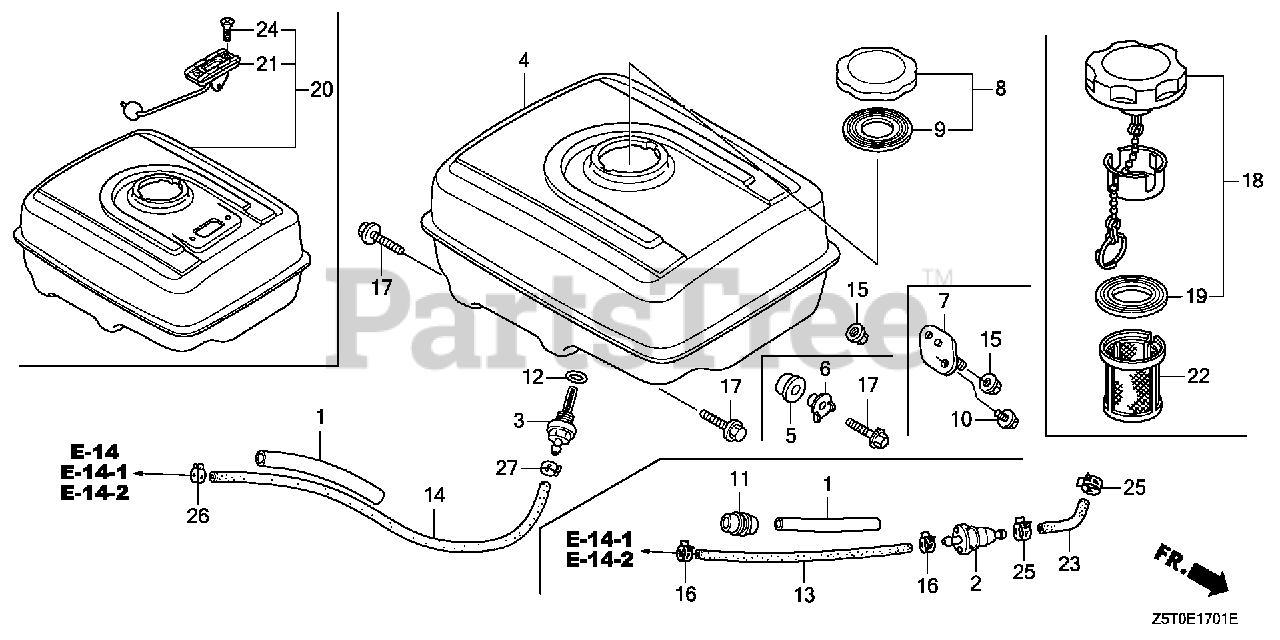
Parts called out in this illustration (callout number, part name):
2	FILTER, FUEL
11	RUBBER, FUEL (9X15X20)
13	TUBE, FUEL (4.2X180) (FKM)
16	CLIP, TUBE (D8)
